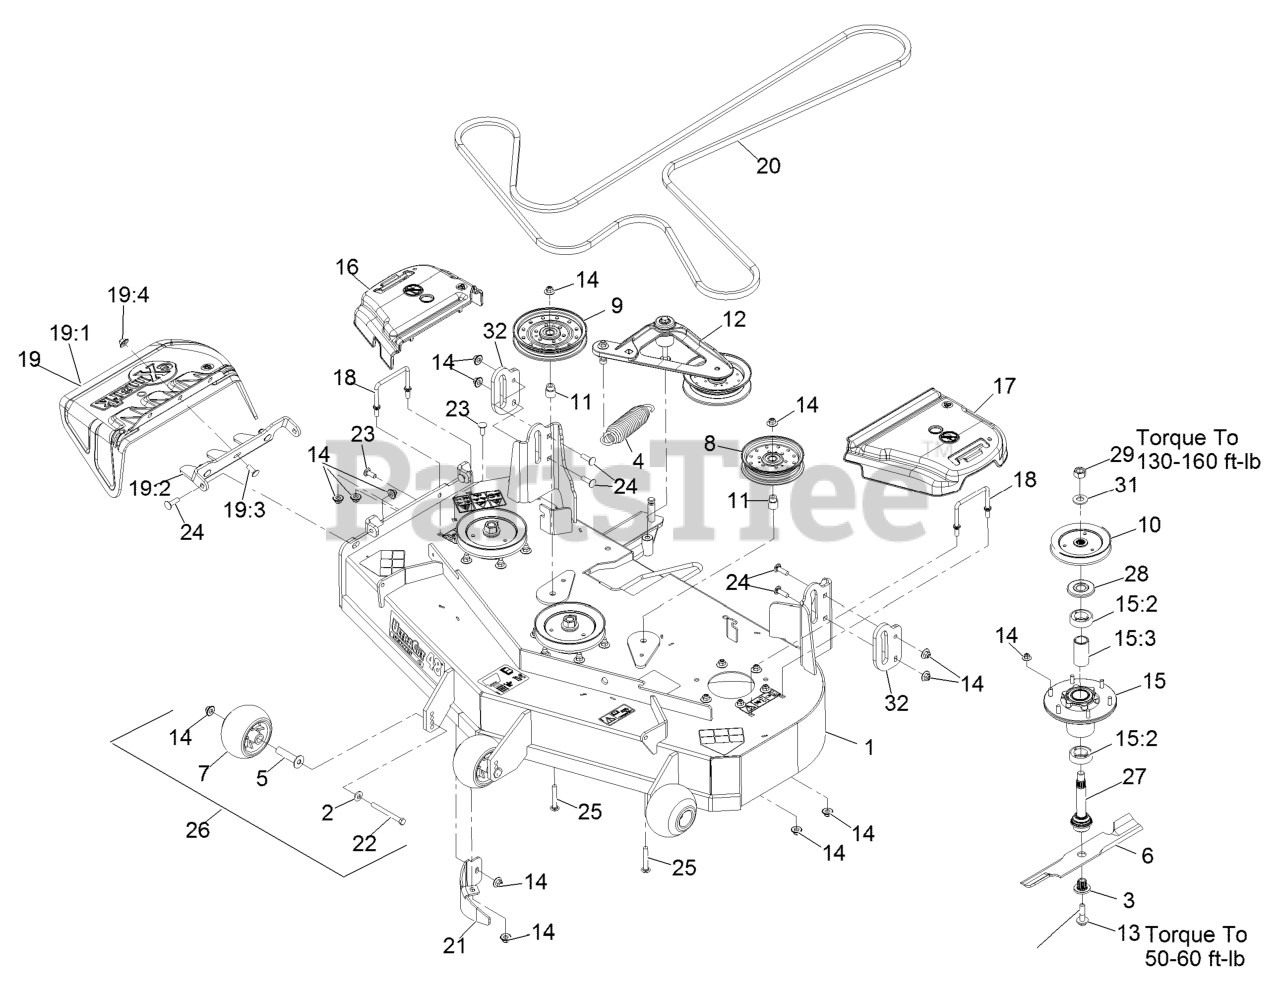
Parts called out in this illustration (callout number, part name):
1	ASM-484 DECK WITH DECALS
2	WASHER-BELLEVILLE
3	BUSHING,SPLINED
4	SPRING-EXTENSION
5	AXLE, ROLLER
7	ROLLER-SCALP, ANTI
10	SHEAVE,BLADE DRIVE 5.90
11	BUSHING-IDLER
12	DECK IDLER ASM
13	SCREW,SEMS 1/2-20 X 2.19
14	Nut-Nyloc 3/8-16 Flg
15	ASM-CUTTER HSG WITH BEARINGS
15:2	BEARING-BALL
15:3	SPACER-BEARING
16	COVER-BELT, RH
17	COVER-BELT, LH
18	WIREFORM-COVER
19	ASM,DISCHARGE CHUTE
19:1	CHUTE,DISCHARGE
19:2	BRACKET,DISCHARGE CHUTE
19:3	SCREW-CARR
19:4	Nut-Nyloc 3/8-16 Flg
20	BELT
21	BAFFLE-DOGLEG,LZE48
22	SCREW-HH 3/8-16 X 3 3/4 GR 8
23	SCREW-CARR
24	Bolt-Carriage 3/8-16 X 1 1/4
25	SCREW-CARR
26	KIT, ANTI-SCALP ROLLER
27	ASM-SPINDLE AND SEAL
28	GUARD,BEARING TOP .989
29	NUT-HEX
32	PLATE-REINF, PUSH TOWER
